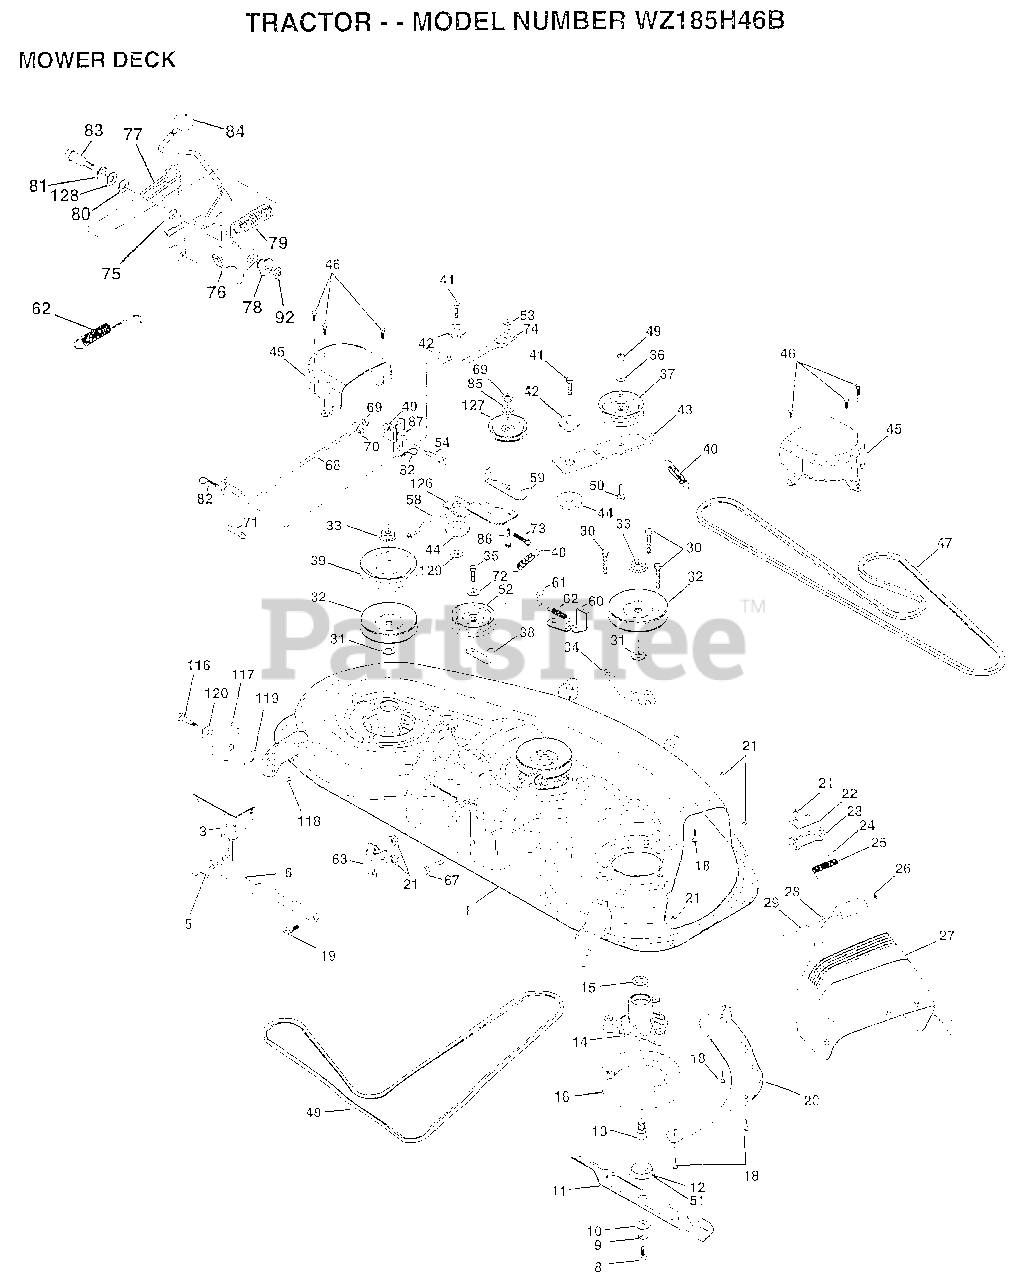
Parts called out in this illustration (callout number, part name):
1	"MOWER ASM 46"""
3	BRKT.ASM.SW.44/50
8	BLADE BOLT
10	WASHER.HARD.BLADE
11	"BLADE.HIGHLIFT46"""
12	BEARING.BALL
13	SHAFT.ASM.W/BRNG
14	HOUSING.MAND.44.V
15	BEARING
16	STRIPPER RND MWR
18	BOLT
19	BOLT SHD 5/16-18
20	BAFFFLE.VORTEX.46
22	STIFFENER BRKT
23	DEFLECTOR BRKT
24	CAP-SLEEVE LT
26	NUT PUSH M
27	SHIELD DEFLECTOR
28	WASHER
29	HINGE ROD
30	"SCREW-THD ROLL,WA"
31	WASHER
32	PULLEY.MAND.36/46
34	ANCHOR.SPRING.46
35	SCREW LT
36	WASHER
37	FLAT IDLER PULLEY
38	"KEEPER BELT,IDLER"
39	PULLEY.DRV.DCK.46
40	"SPRING.SEC.44""VEN"
41	SCREW
42	SPACER RETAINER
43	ARM.IDLER.DECK.46
44	HARDENED WASHER
45	COVER.MANDREL.46
46	SCREW.1/4-20X5/8
47	BELT-V.SEC.46.KEL
48	V BELT MOWER
50	BOLT.3/8-16X1.50
51	WASHER.FELT.
52	"PULLEY IDLER,FLAT"
53	WASHER
54	BOLT
58	"LINK BRAKE, 43"""
59	"GUIDE BELT,46""MOW"
60	ARM ASM BRAKE
61	BOLT.SHOULDER.5/16-18
62	RETURN SPRING
63	"BRKT ROD,CLUTCH"
67	BOLT
69	NUT
70	TRUNION ADJ
71	PIVOT ROD
72	WASHER
73	COTTER PIN
74	LINK CLUTCH
75	CLUTCH ARM SECOND
76	LEVER.ASM.CLUTCH
77	SPRING KEEPER
78	BUSHING
79	SPRING.CLUTCH.MWR
80	WASHER
81	RING
82	RETAINER M
84	KNOB.RD.7/16-14
85	LOCKWASHER
86	"BOLT CARR, SH"
87	BRACKET.EXTENSION
92	NUT
116	BOLT M
117	WHEEL.GAGE.BLK.PL
118	LOCKNUT
119	WASHER
120	WASHER
127	PULLEY.IDLER.4.25
128	WASHER .T
129	WASHER T
